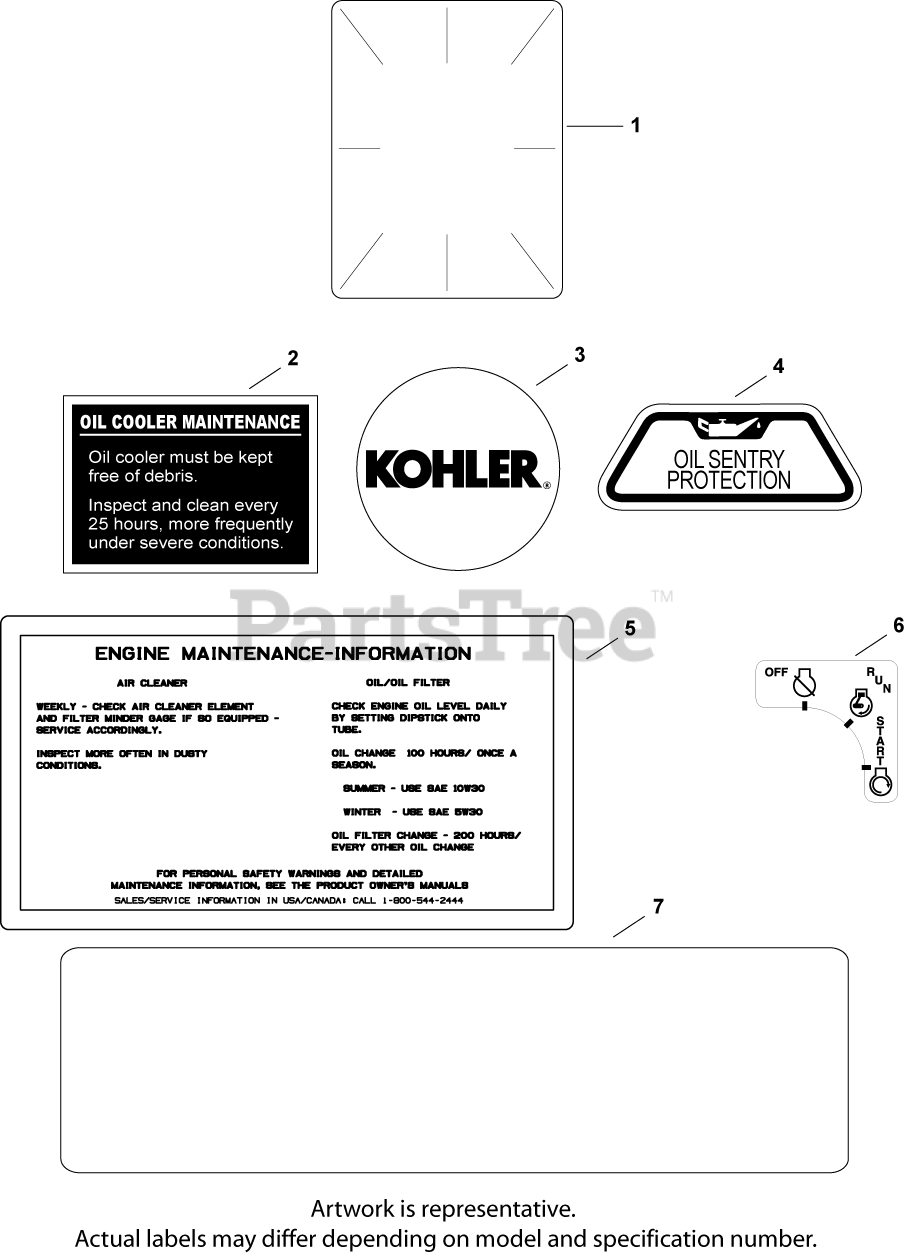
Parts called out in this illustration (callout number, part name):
1	DECAL, CLEAR LAMINATE USE 25 113 70-S
2	DECAL, OIL COOLER - (#DSC)
3	LABEL, (ROUND KOHLER GOLD)-USE 24 113 18
4	DECAL, OIL SENTRY - (#DSC)
5	DECAL, AIR CLEANER - (#DSC)
6	DECAL, KEY SWITCH
7	DECAL, 27 HP
